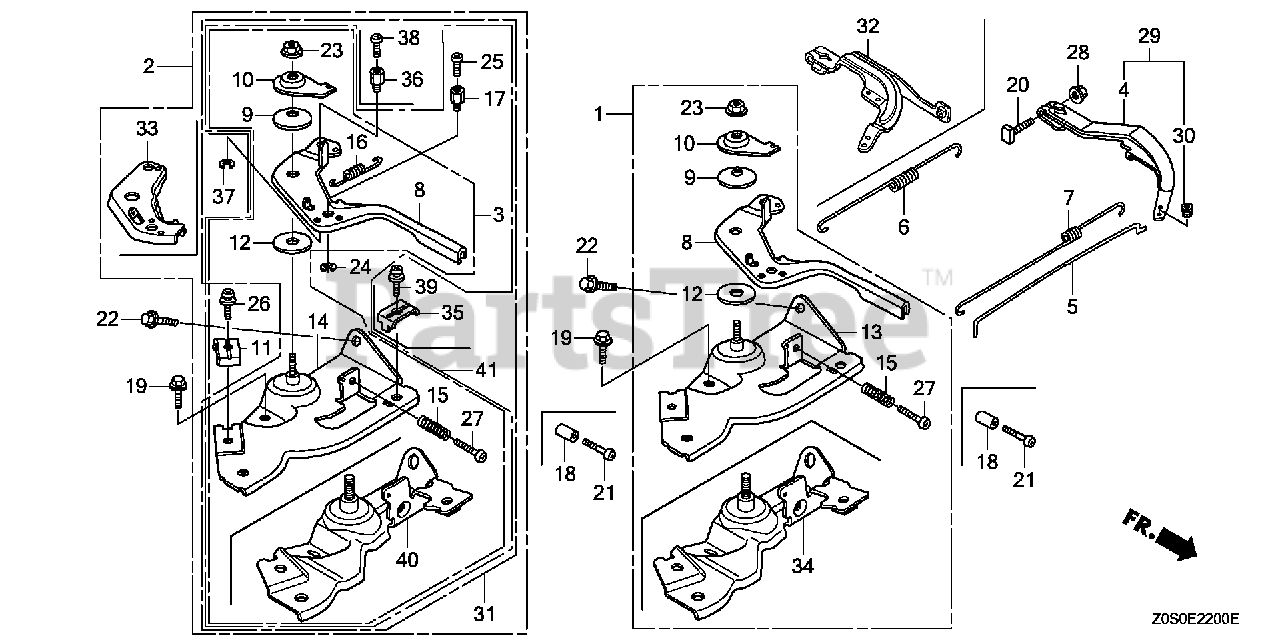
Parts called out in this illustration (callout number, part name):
4	ARM, GOVERNOR
5	ROD, GOVERNOR
6	SPRING, GOVERNOR
7	SPRING, THROTTLE RETURN
8	LEVER, CONTROL
9	SPRING, LEVER
10	WASHER, CONTROL LEVER
12	SPACER, CONTROL LEVER
15	SPRING, CONTROL ADJUSTING
19	BOLT, FLANGE (6X12) (CT200)
20	BOLT, GOVERNOR ARM
22	BOLT, FLANGE (6X20) (CT200)
23	NUT, SELF-LOCK (6MM)
27	SCREW, PAN (5X25)
28	NUT, FLANGE (6MM)
